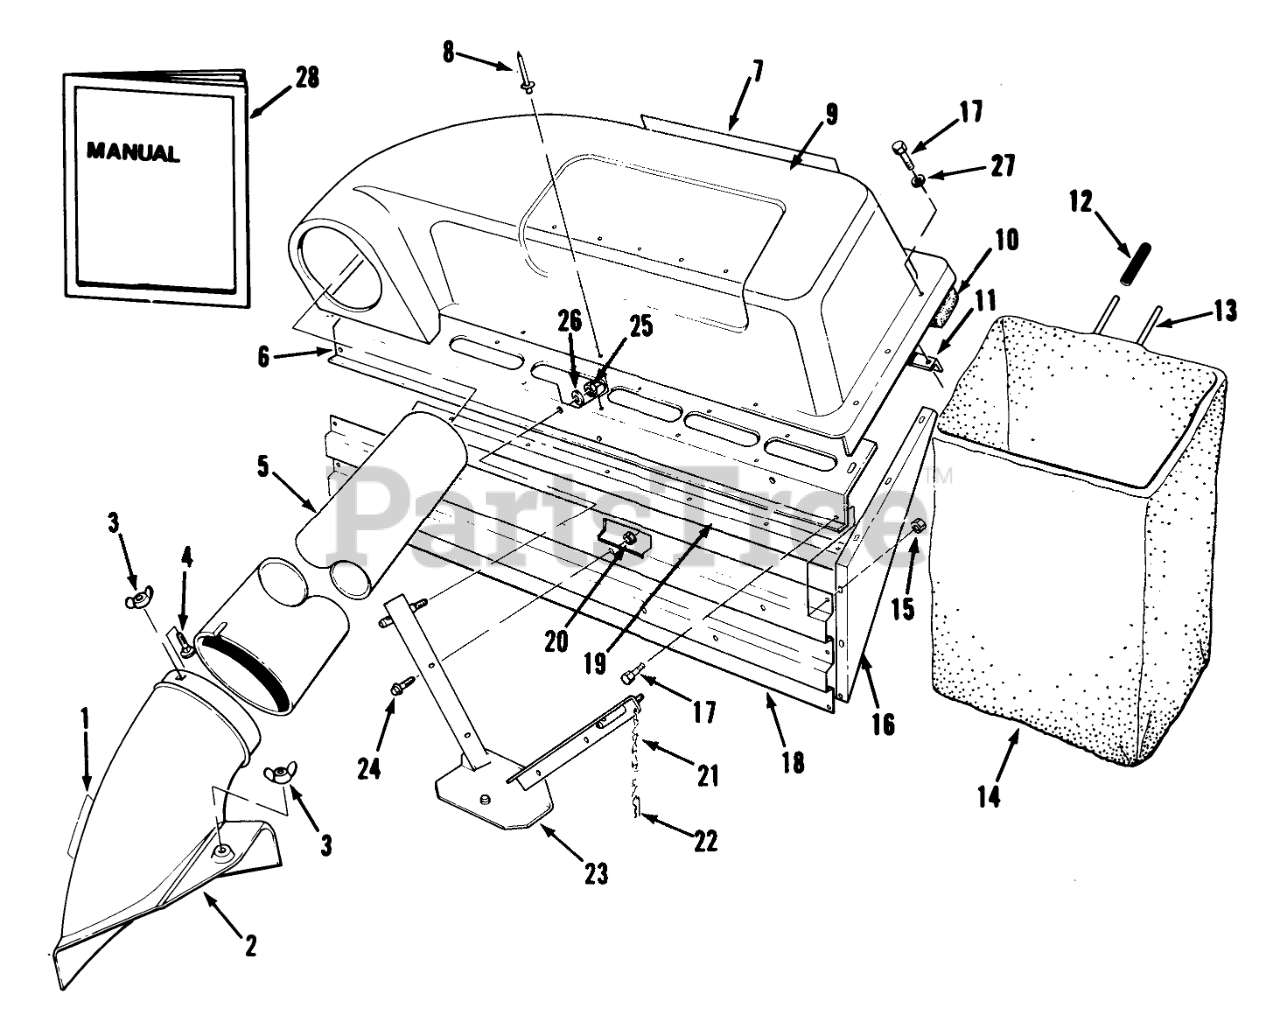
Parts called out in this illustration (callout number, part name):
1	DECAL-DANGER
2	Chute
3	NUT-WING SPECL
4	BOLT-CARR
6	COVER SUPT BAFFLE B
7	Decal-Twin Bagger
8	RIVET-POP
9	COVER
10	FOAM SEAL
11	BAG FRAME BRKT
12	GRIP-HANDLE, BAG
13	BAG FRAME
15	NUT-LOCK, NI
16	Plate-Side
17	SCREW-HH
18	MUFFLER SHIELD
19	BAG SUPPORT CHANNEL
20	NUT-LOCK, NI
21	6-LINK CHAIN W/HOOK
22	PIN-HAIR
23	V-Bracket
24	SCREW-HH
25	NUT-LOCK, NI
26	WASHER-FLAT
27	WASHER-FLAT
28	INSTRUCTION SHEET
